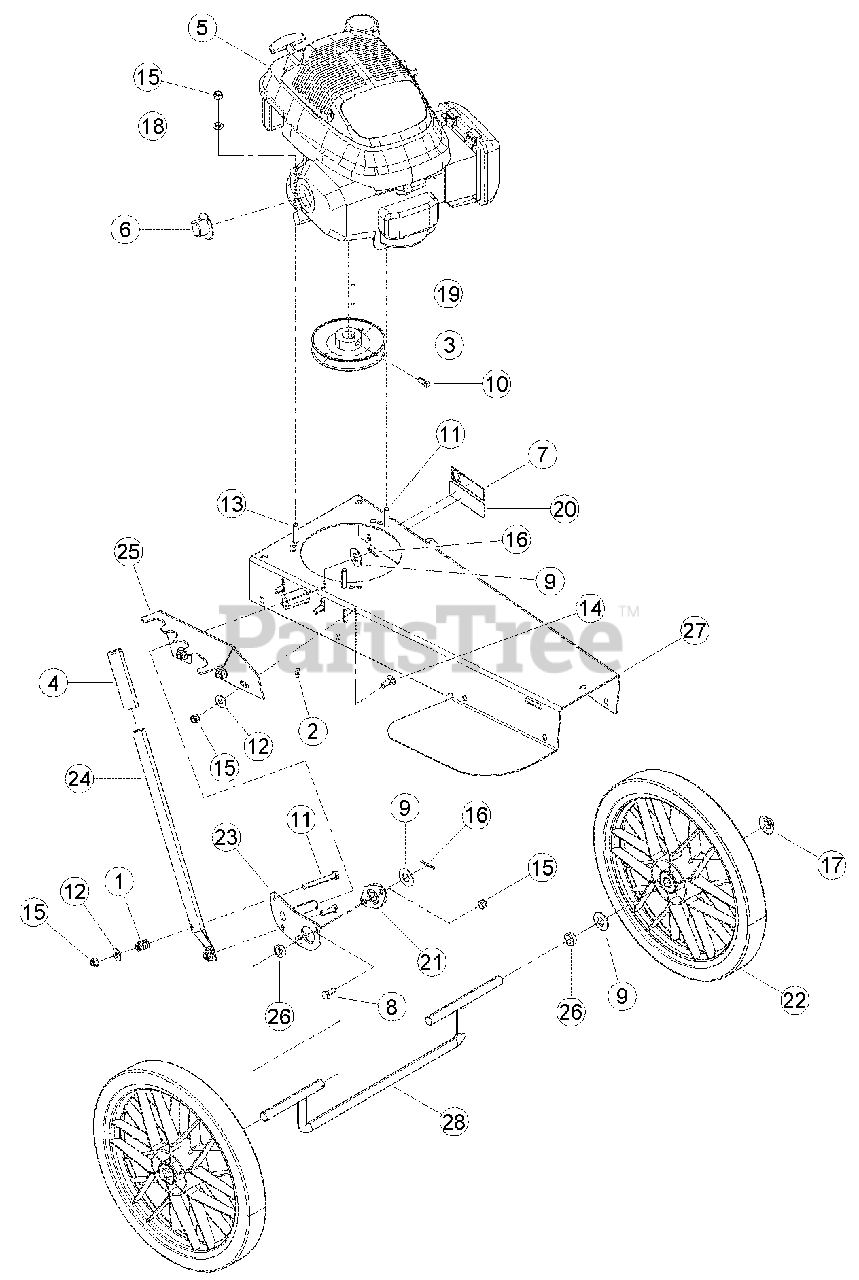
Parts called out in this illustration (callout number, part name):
1	SPRING, HEAVY DUTY COMPRESSION
2	FITTING, 1/4 SELF-TAP GREASE
3	PULLEY, 5.0 X 7/8 AB
4	GRIP, TILT CONTROL
5	ENGINE, 6.5 HP QUANTUM HD 49 STATE
6	DEFLECTOR, EXHAUST
7	DECAL, 5.5 HP INFORMATION
8	BOLT, 5/16 X 3/4 HEX HD GR5 ZP
9	WASHER, 5/8 SAE FLAT ZP
10	SCREW, 5/16-18 X 5/8 SQ HD SET
11	BOLT, 5/16 X 2-1/2 HEX HD GR5 ZP
12	WASHER, 5/16 FLAT ZP
13	BOLT, 5/16 X 1-1/2 HEX HD GR5 ZP
14	BOLT, 5/16 X 7/8 CRG GR5 NC ZP
15	NUT, 5/16 NE NYLOCK ZP
16	PIN, 1/8 X 1.00 COTTER ZP
17	PUSHNUT, 5/8 ZP
18	WASHER, 5/16 SAE FLT ZP
19	KEY, 3/16 SQUARE X 1-1/2 LONG PLAIN
20	DECAL, SERIAL NUMBER
21	BEARING, SIDE FLANGE MOUNT, 5/8
22	WHEEL, 15 INCH TRIMMER (BLACK)
23	WELDMENT, AXLE PIVOT
24	HANDLE, TRIMMER HEIGHT ADJUST
25	PLATE, HANDLE LOCK
26	SPACER, 7/8 X .281
27	WELDMENT, TRIMMER BODY
28	WELDMENT, TRIMMER AXLE
